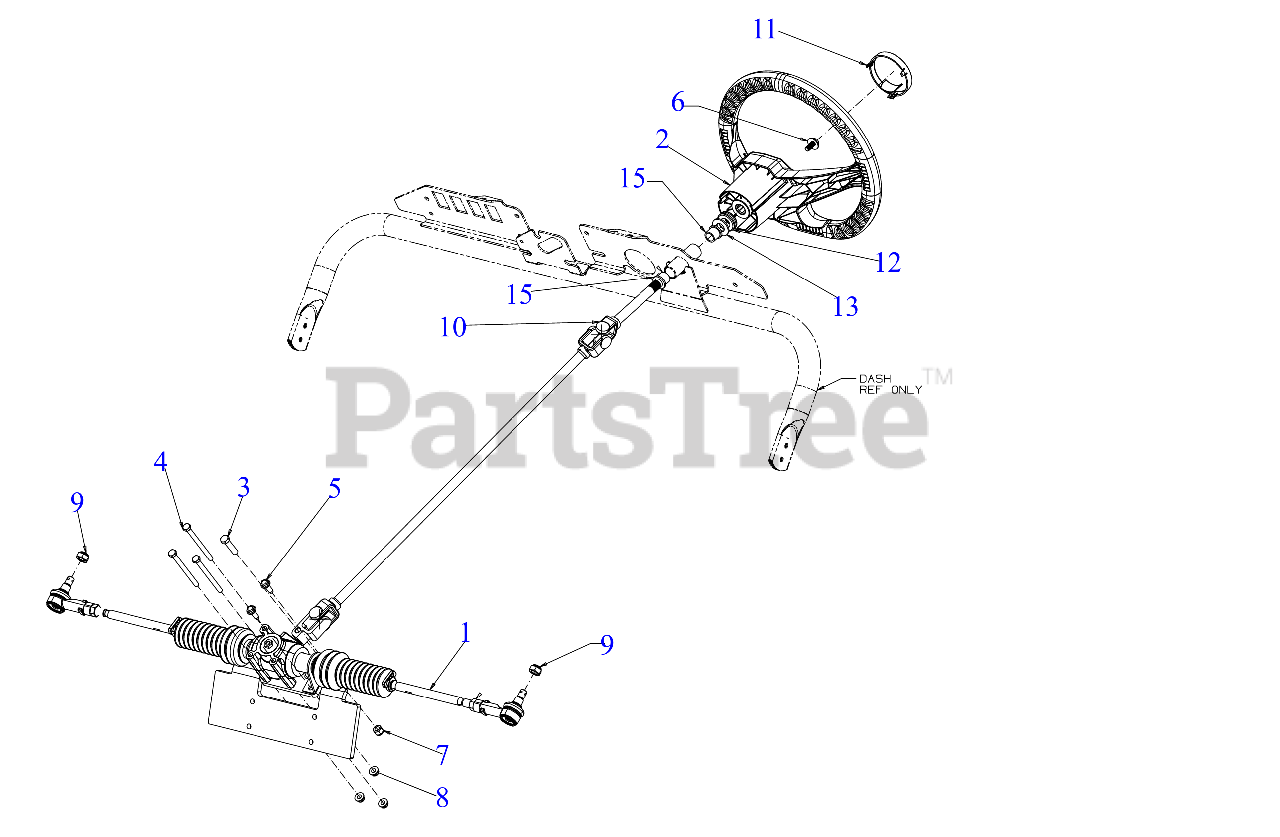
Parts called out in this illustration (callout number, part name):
1	STEERING GEARBOX ASSEMBLY
2	STEERING WHEEL
3	SCREW 3/8-16 x 1.50
4	SCREW 5/16-18 x 4.00 GR5
5	SCREW 5/16-18 x 1.00
6	SCREW 5/16-24 x .85 GR5
7	HEX NUT INS L-3/8-16
8	FLANGE LOCK NUT 5/16-18
10	STEERING SHAFT ASSEMBLY
11	STEERING WHEEL CAP
12	RUBBER GROMMET
13	FLAT WASHER .656 x 1.312 x .097
15	FLANGE BEARING
